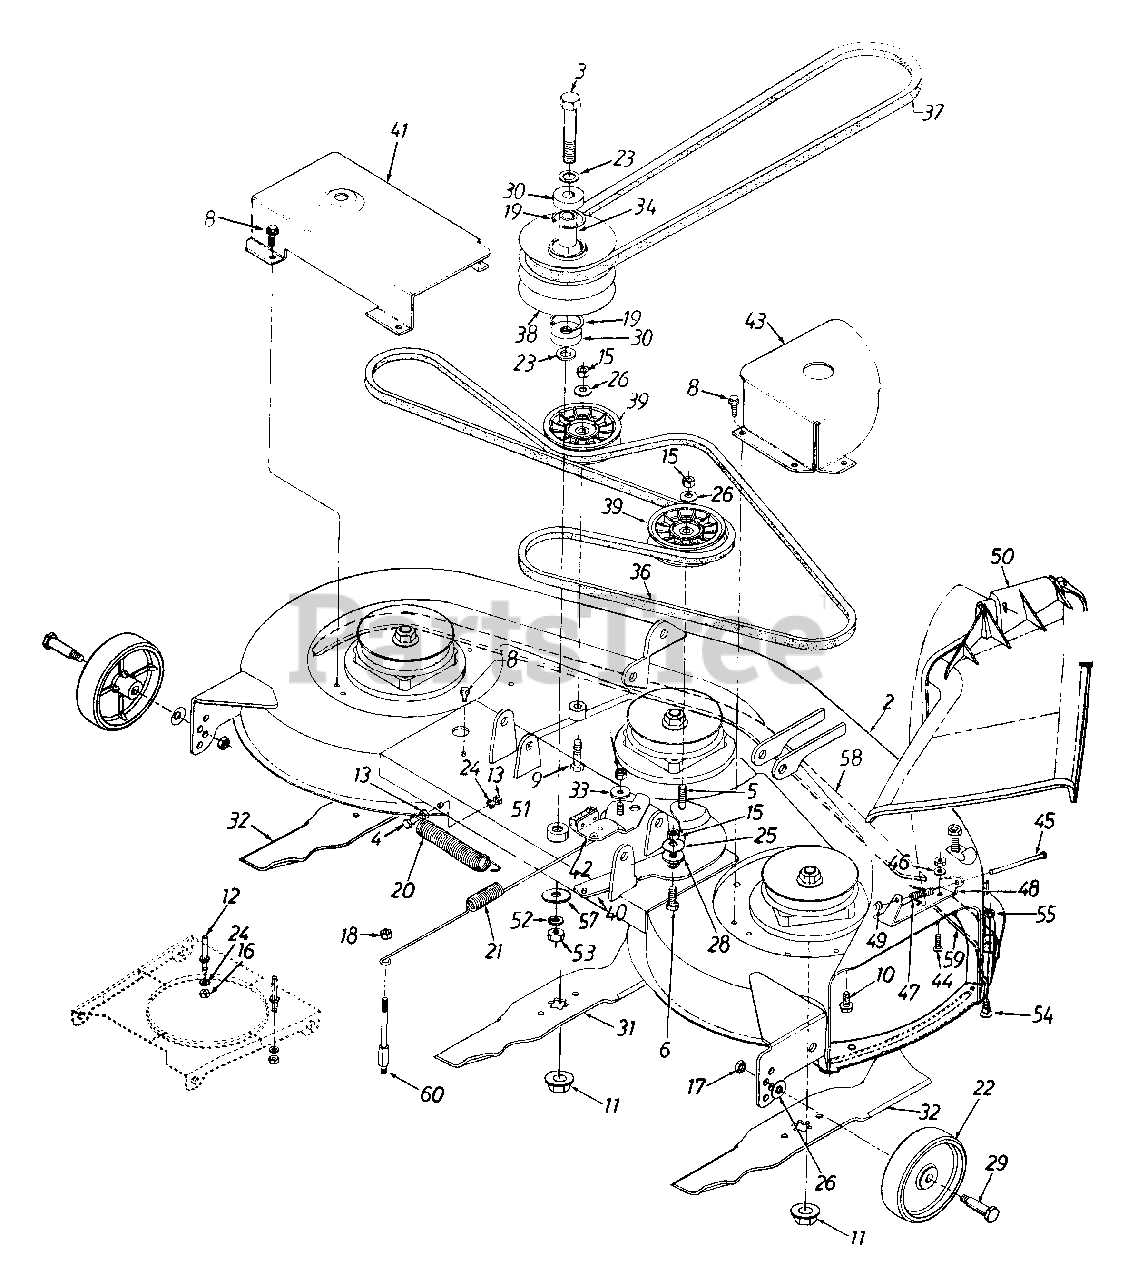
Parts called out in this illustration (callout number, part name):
4	Hex Bolt 1/4-28 x 1.25" Lg.
5	Hex Bolt 3/8-24 x 1.5" Lg.
6	Hex Bolt 3/8-24 x 1" Lg.
8	Hex Wash. Hd. TT-Tap Scr.
9	Hex Bolt 3/8-24 x 2" Lg.
10	Hex Flange Bolt 5/16-24 x .75"
11	Hex Flange L-Nut 5/8-18 Thd.
12	Belt Guard Pin
13	Hex Nut 1/4-28 Thd.
15	Hex Nut 3/8-24 Thd.
16	Hex Nut 1/4-20 Thd. (Gr. 5)
17	Hex Top Jam Nut 3/8-16 Thd.
18	Hex Center L-Nut 5/16-18 Thd.
19	Int. Snap Ring
20	Ext. Spring .88" O.D. x 6.17"
21	Ext. Spring .788" O.D. x 15.5"
22	Deck Wheel
23	Fl-Wash. .635" I.D. x 1" O.D.
24	L-Wash. 1/4" I.D.
25	Bell-Wash. 3/8" x 1.125" x .062"
26	Bell-Wash. 3/8" x .87" x .064"
28	Shoulder Spacer .625" I.D.
29	Shld. Bolt .498" x 1.525"
30	Ball Brg. .625" I.D. x 1.574" O.D.
31	Blade 14.88" Lg.
32	Blade 16.28" Lg.
33	Shoulder Spacer
34	Spacer .635" I.D. x .088" O.D.
36	V-Belt
37	V-Belt
38	Pulley Double Deck 5" O.D.
39	Flat Idler Pulley 3.5 O.D.
44	Hex Bolt 1/4-20 x .62" Lg.
45	Hinge Pin
46	Bell-Wash. 1/4" I.D.
47	Torsion Spring
48	Hinge Mtg. Brkt.
49	Push Nut
50	Chute Ass'y. Comp.
51	Spacer .635" I.D. x 1" O.D.
52	L-Wash. 5/6" I.D.
53	Hex Nut 5/8-18 Thd.
54	Carriage Bolt 1/4-20 x .5" Lg.
55	Hex Sems Nut 1/4-20 Thd.
57	Fl-Wash. .635" I.D.
60	Return Spring Stud
